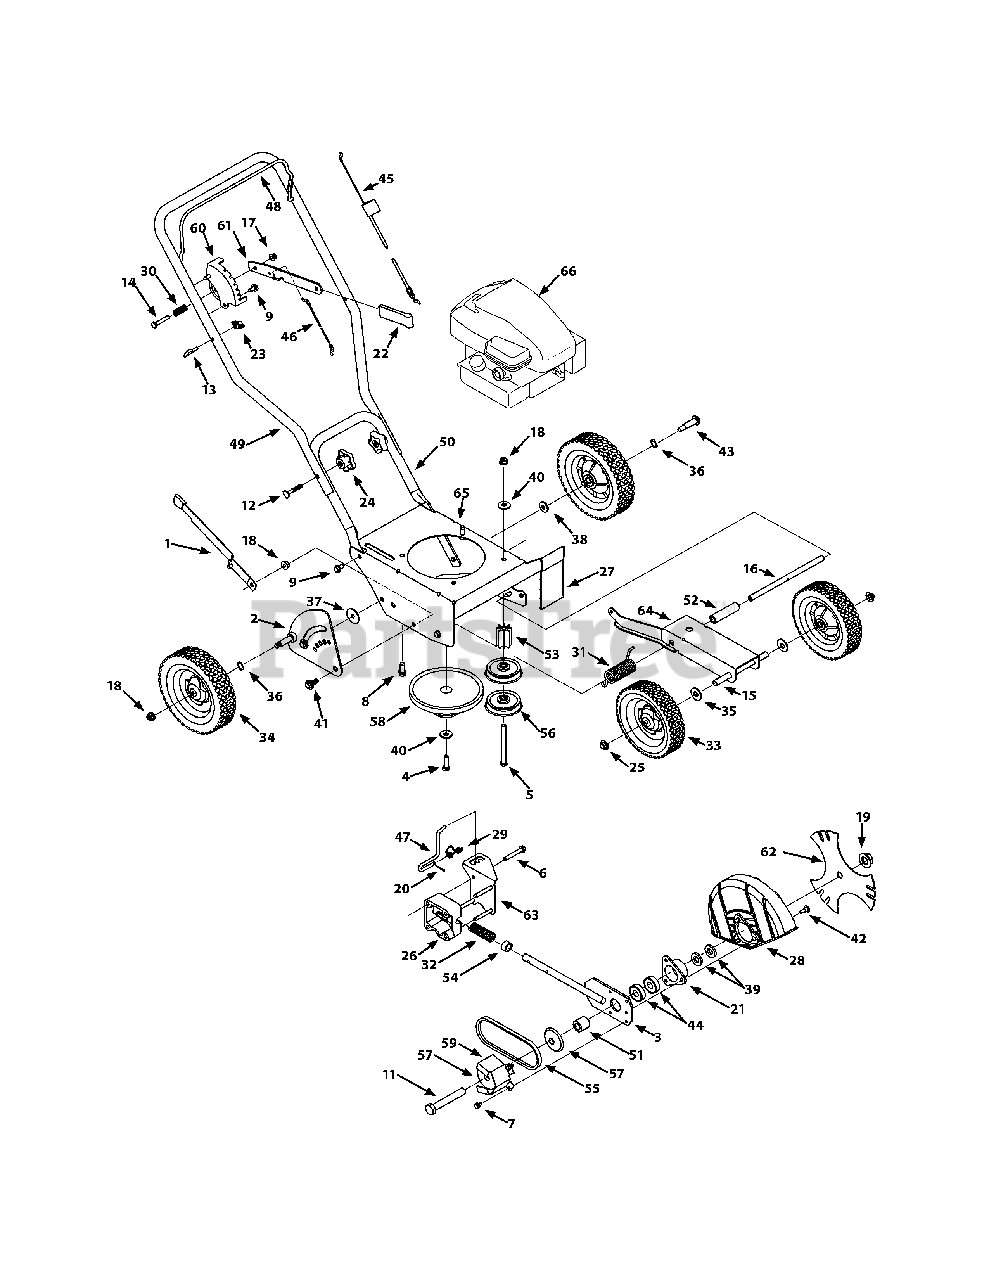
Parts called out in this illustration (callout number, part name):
1	Curb Height Adjustment Lever
2	Curb Height Adjuster Plate
3	Blade Plate Assembly
4	Screw 3/8-24
5	Screw 3/8-16
6	Hex Screw, 5/16-18
7	Self-tapping Screw, 1/4-20
8	Screw, 3/8-16
9	Hex Screw, 5/16-12
10	Hex Screw 5/16-18
11	Hex Screw, 5/8-18
12	Carriage Bolt, 5/16-18
13	Rope Guide (Eye Bolt)
14	Hex Screw, 5/16-18
15	Axle Shaft .50x6.65
16	Frame Spacer .50x9.25
17	Lock Flange Nut, 5/16-18
18	Flange Nut 3/8-16
19	Flange Nut, 5/8-18
20	Clevis Pin 3/32 x .625
21	Bearing Cup
23	Wing Nut
24	Star Knob
25	Push Cap 1/2" rod
26	Bearing Block
27	Debris Guard
28	Blade Guard
29	Double Torsion Spring
30	Compression Spring
31	Torsion Spring
32	Compression Spring
33	Wheel 7 x 1.75 T-Tread
34	Wheel 8 x 1.75 T-Tread
35	Flat Washer 1/2 x 1.25 x .10
36	Wave Washer .531 x .781 x .013
37	Flat Washer, .385 x 1.5 x .075
38	Flat Washer .385 x 1.0 x .135 †
39	Flat Washer .635x1.24x.181
40	Bell Washer,.396 x 1.140
41	Shoulder Screw, 3/8-16
42	Shoulder Screw
43	Shoulder Screw, 3/8-16
44	Bearing, .625 ID x 1.57 OD
45	Control Cable (Briggs & Stratton)
46	Wheel Adjustment Cable
47	Blade Adjustment Rod
48	Bail Handle
49	Upper Handle
50	Lower Handle
51	Spacer, .63 x 1.12 x 1.06
52	Spacer
53	Pulley Mount Spacer
54	Spacer, .64 x.88 x .50
56	Flat Idler Pulley, 2.5 OD
57	Sheave
58	Combination Flywheel Pulley
59	Belt Guard
61	Depth Index Lever
62	Tri-Star Blade
63	Bracket Plate
64	Dual Wheel Bracket
66	Engine 10L802-0713-F1
